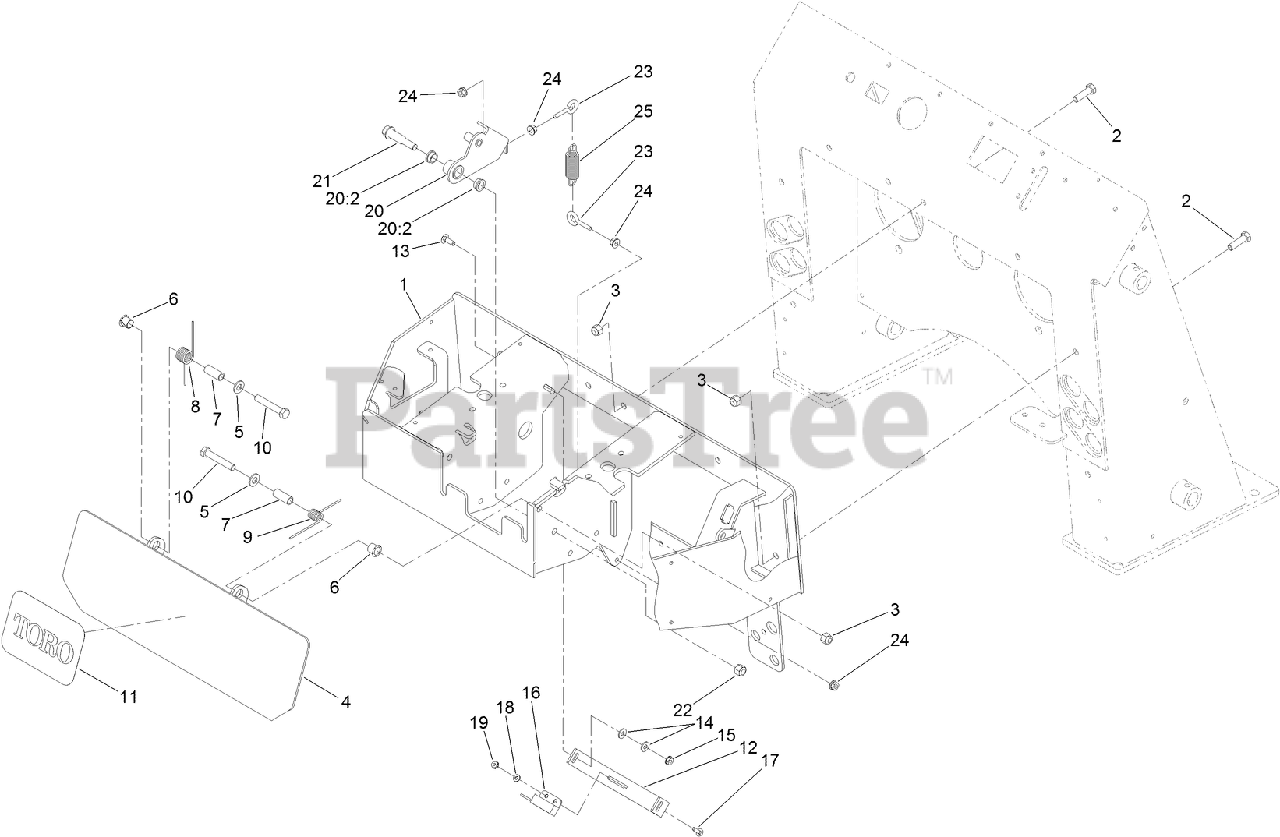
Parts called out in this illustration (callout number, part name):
1	PANEL-CONTROL
2	SCREW-HH
3	NUT-LOCK, NI
4	PLATE-REVERSE
5	WASHER-FLAT
6	BUSHING-NYLINER
7	SPACER-SPRING
8	SPRING-TORSION, RH
9	SPRING-TORSION, LH
10	SCREW-HH
12	PLATE-SWITCH
13	BOLT-CARR
14	WASHER-FLAT
15	NUT-KEPS
16	SWITCH-PROXIMITY
17	SCREW-CARR
18	WASHER-FLAT
19	NUT-KEPS
20	NEUTRAL CENTERING LEVER ASM
20:2	BUSHING-FLANGE
21	BOLT-SHOULDER
22	NUT-LOCK
23	BOLT-EYE
24	NUT-HHF
25	SPRING-EXTENSION
